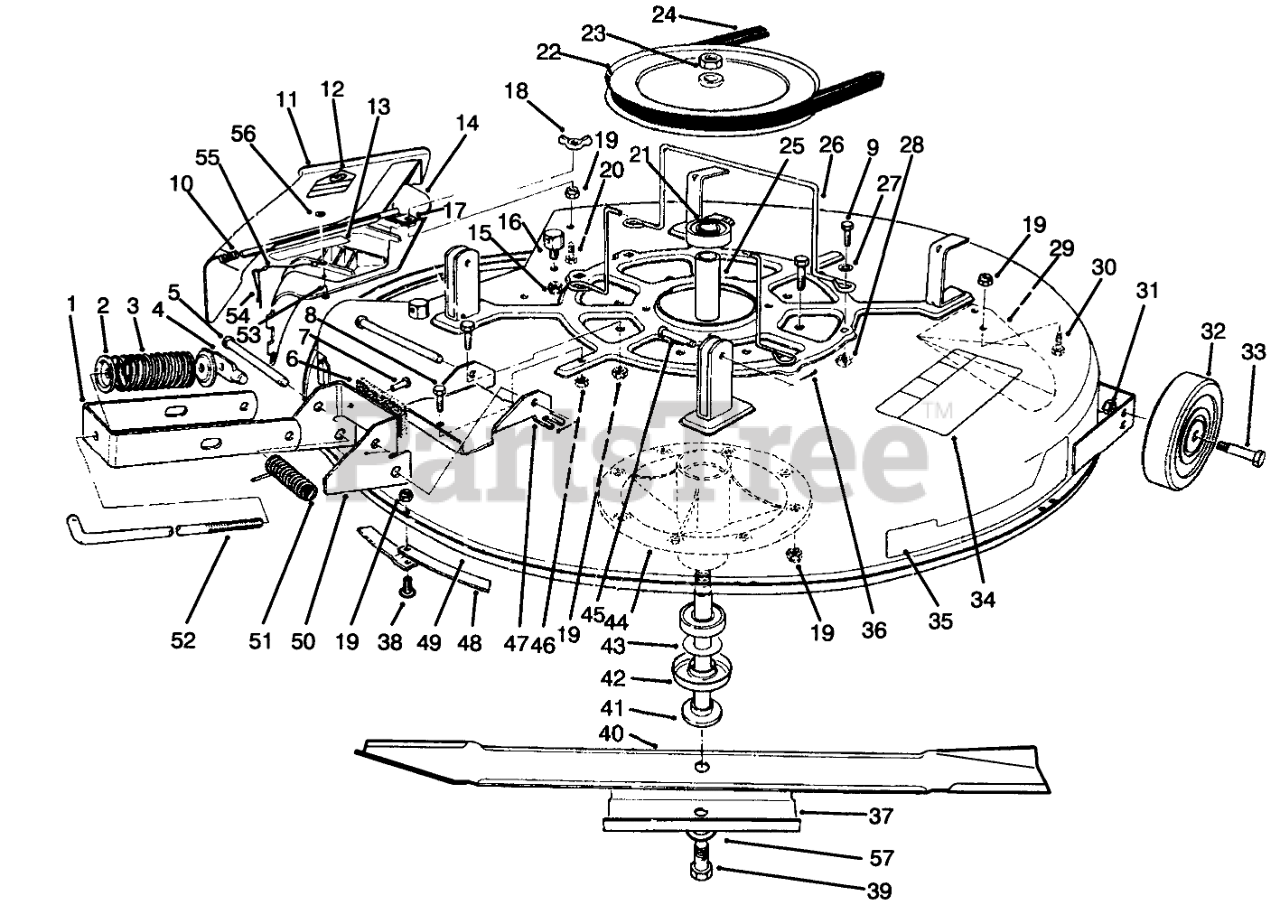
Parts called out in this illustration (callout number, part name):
1	Bracket-Engagement
2	RETAINER-SPR. TOP
3	SPRING-COMPRESSION
4	SHAFT-DECK ADJ.
5	PIN-CLEVIS
6	PAD-BRAKE
7	RIVET-BLIND
8	SCREW-HH
9	SCREW-HH
10	SPRING
11	Assembly-Deflector (Incl. Ref. #12)
12	DECAL-DANGER
13	DECAL-DANGER, DEFLECTOR
14	Assy.-Cover, Discharge (Incl. Ref. #53-56)
15	NUT-LOCK, NI
16	POST-PIVOT
17	Brace-Cover, Rear
18	NUT-WING
19	NUT-LOCK, NI
20	SCREW-HH
21	BEARING-BALL
22	PULLEY
23	NUT-HEX
24	V-BELT, DECK
25	SPACER-BEARING
26	GUIDE-BELT
27	WASHER-PLAIN
28	NUT-RETAINER
29	Kicker
30	SCREW-HH
31	NUT-LOCK, NI
32	WHEEL-DECK
33	BOLT-WHEEL
34	DECAL-DANGER, THROWN OBJECT
35	DECAL - RECYCLER 32"
36	PIN-COTTER
37	STIFFENER
38	SCREW-PPH
39	SCREW-HH
40	BLADE-RECYCLER
41	SHAFT-SPINDLE
42	SHIELD-BEARING
43	SPACER-HARDNED
44	SPINDLE
45	PIN-CLEVIS
46	NUT-HEX
47	Plate-Deck, Brake Mtg.
48	RING-DECK
49	Deck-Cutting
50	Assembly-Brake (Incl. Ref. #6-7)
51	SPRING
52	ROD-ENGAGEMENT
53	RIVET-BLIND
54	PIN-LOCKING, CHUTE
55	LANYARD
56	WASHER-PLAIN
57	WASHER-BELLEVILLE
